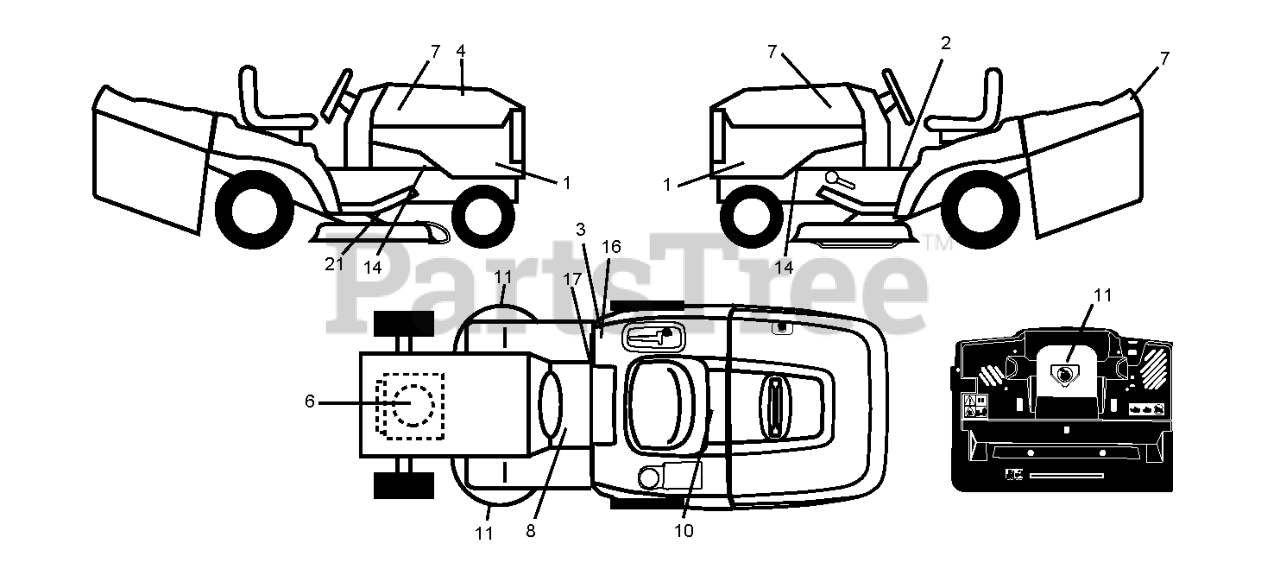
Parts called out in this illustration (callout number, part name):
1	DECAL.SDPNL.LT2218A.BRIGGS.
2	LABEL
3	DECAL 80 DBA
6	DECAL
7	RP.DECAL.BADGE.170MM.TEXTLOGO
8	DECAL
10	DECAL BTRY SYMBOLS
11	DECAL.INTERNATIONL.CUTFINGER
16	DECAL
17	DECAL PARK BRAKE
